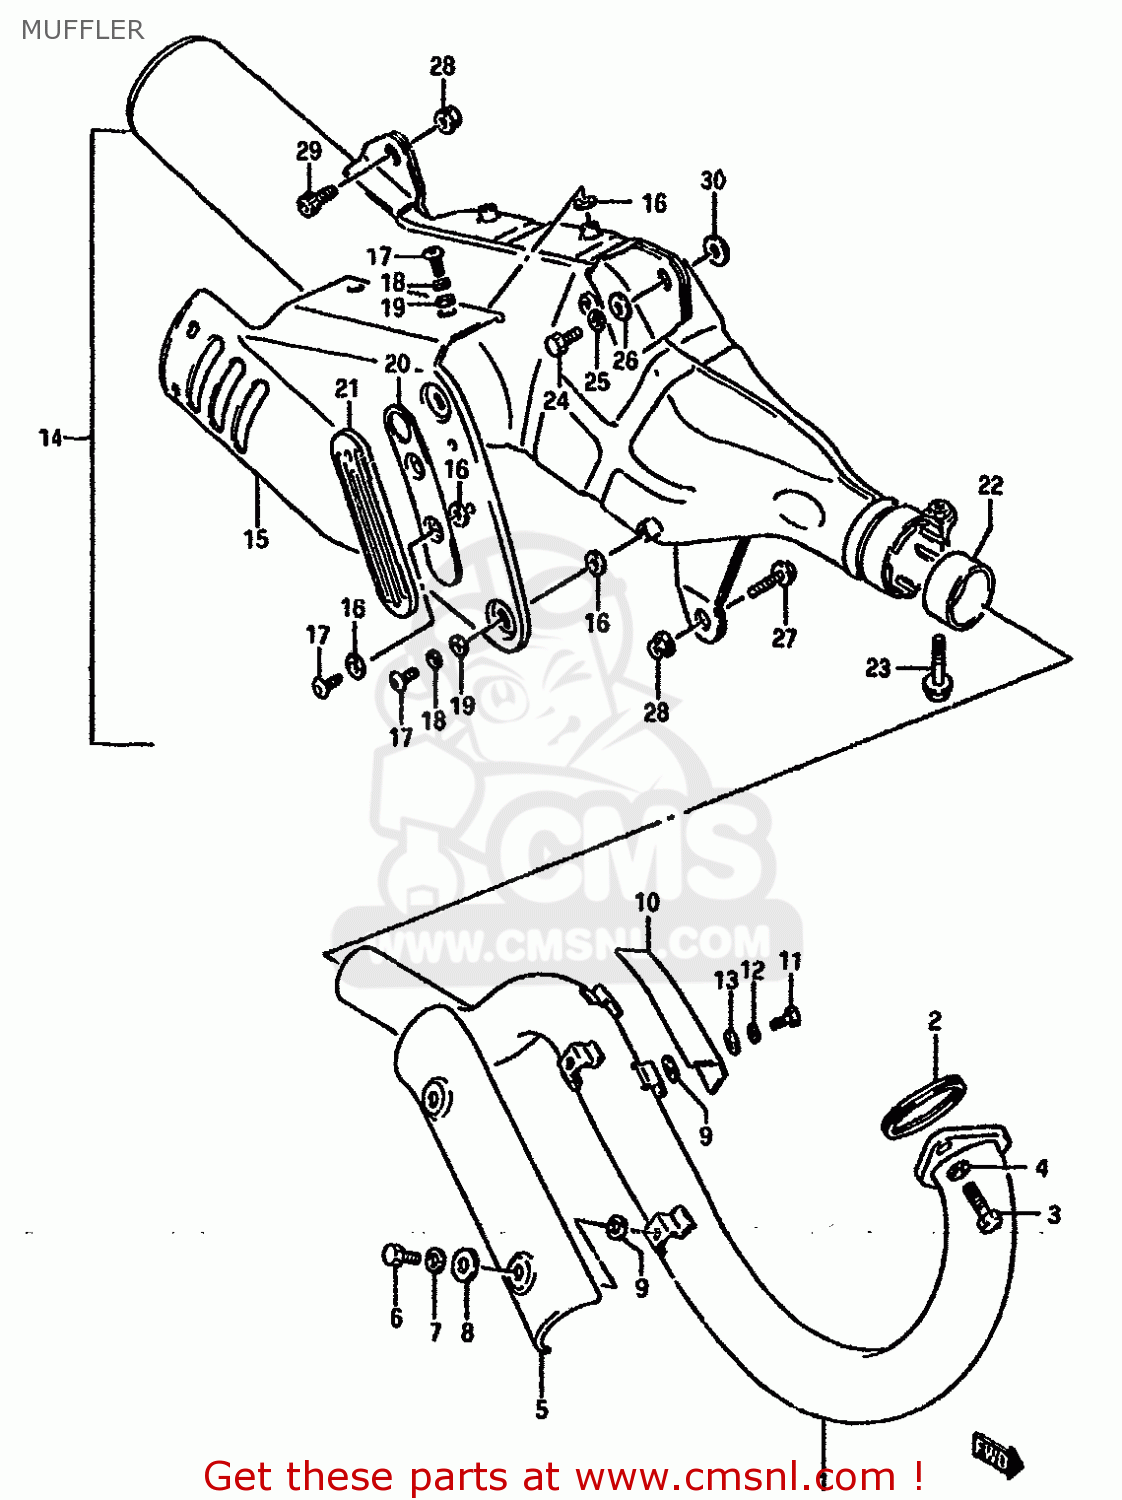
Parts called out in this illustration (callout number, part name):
1	PIPE,EXHAUST
2	GASKET,EXHAUST PIPE (NAS)
3	BOLT
4	WASHER,LOCK,8.
5	COVER,EXHAUST PIPE
6	BOLT
7	WASHER,LOCK
8	WASHER
9	GASKET (NAS)
10	PLATE,HEAT GUARD
11	BOLT 6X16
12	WASHER,LOCK
13	WASHER
14	MUFFLER ASSY
15	COVER,MUFFLER
16	GASKET (NAS)
17	SCREW(6X10)
18	WASHER,LOCK
19	WASHER(6.5X18X1)
20	GUARD,MUFFLER COVER
21	COVER,MUFFLER COVER GUARD
22	CONNECTOR,MUFFLER
23	BOLT 8X40
24	BOLT
25	WASHER,LOCK,8.
26	WASHER
27	BOLT
28	NUT
29	BOLT
30	WASHER(8X20X1)
